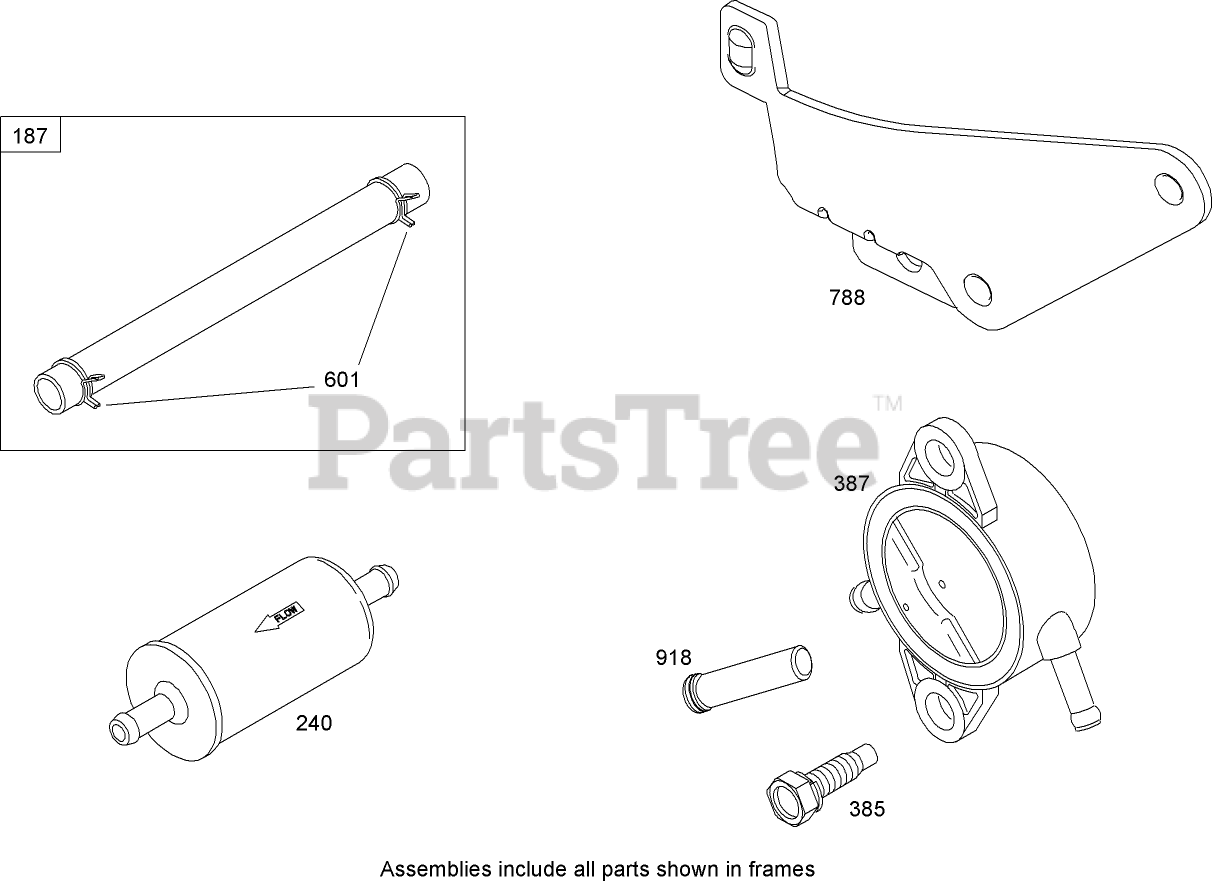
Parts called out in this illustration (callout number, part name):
187	Line-Fuel (Cut to required length)
240	Filter?Fuel
385	Screw
387	Pump-Fuel
601	Clamp-Hose
788	Bracket-Pump, Fuel
918	Hose-Vacuum
